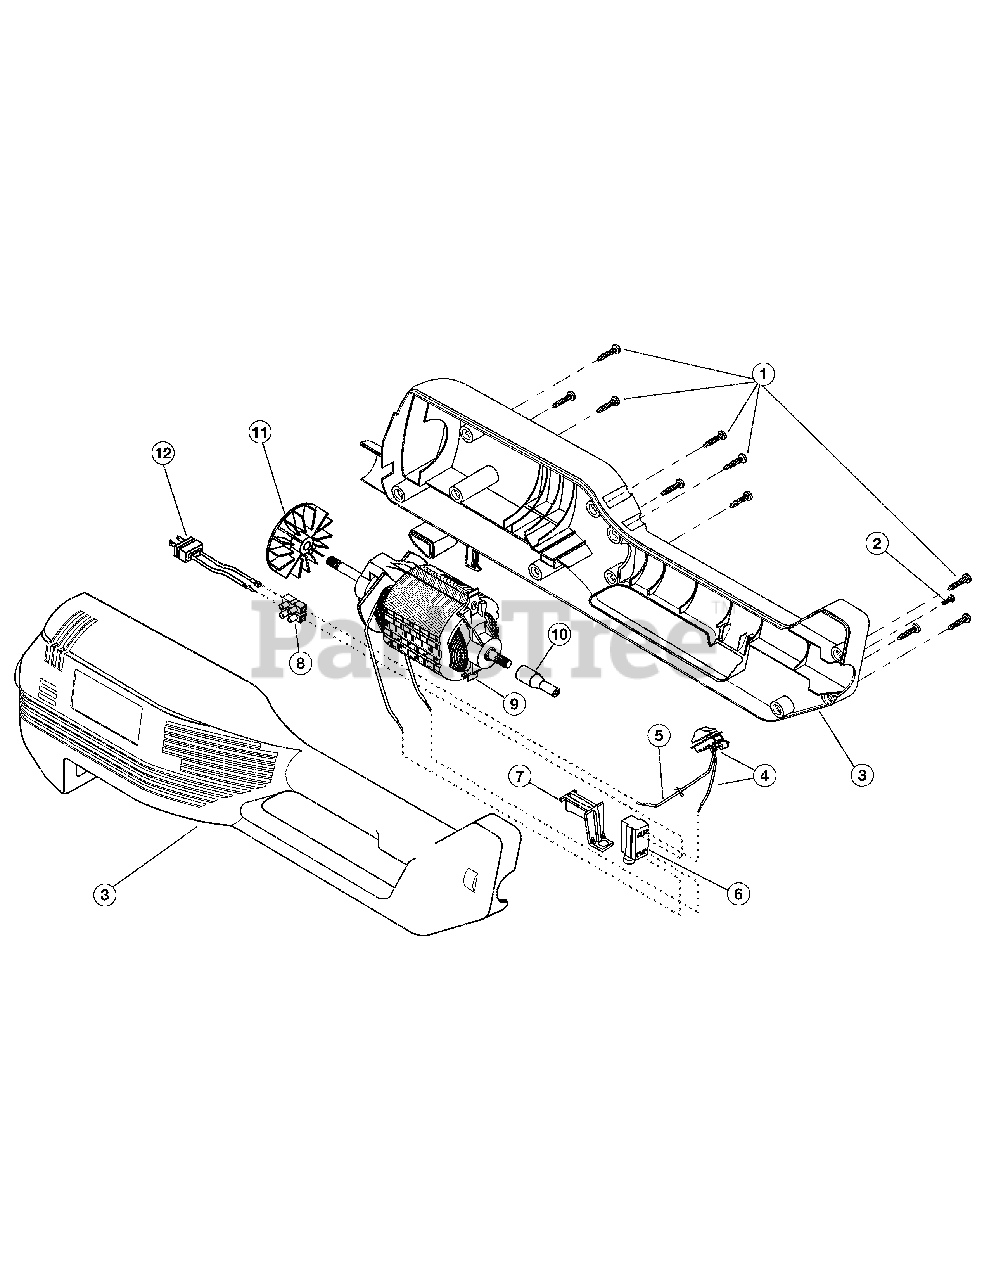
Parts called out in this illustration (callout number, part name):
1	Screw, Housing Set (Qty. 10)
2	Anti-Rotation Screw
3	Motor Housing Assembly
4	Two-Speed Switch Assembly
6	Switch (includes 7)
8	Terminal Block
9	Motor Assembly (includes 10 & 11)
11	Cooling Fan
12	Recessed Plug Assembly
